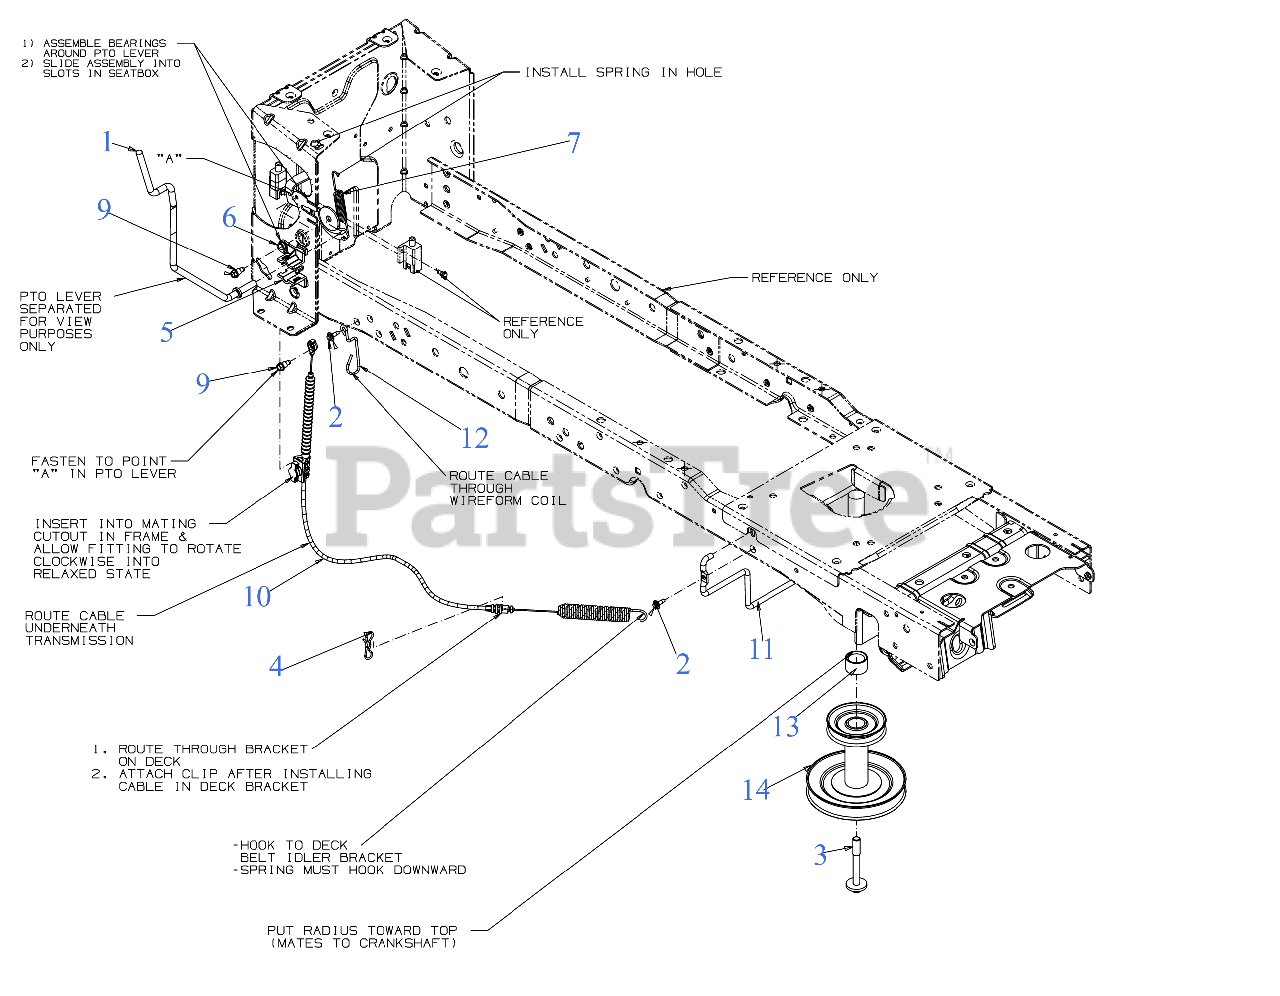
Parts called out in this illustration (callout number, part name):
1	PTO HANDLE ASSEMBLY
2	SCREW M6-1 x .625
3	SCREW 7/16-20 x 3.50
4	BOW TIE COTTER PIN
5	PTO HANDLE BOTTOM BEARING
6	PTO HANDLE TOP BEARING
7	EXTENSION SPRING .56 OD x 4.52
9	SHOULDER SCREW
10	PTO HANDLE CABLE
11	BELT KEEPER ROD
12	CABLE GUIDE WIRE
13	ENGINE PULLEY SPACER
14	ENGINE PULLEY 3.56 x 6.12 DIA
